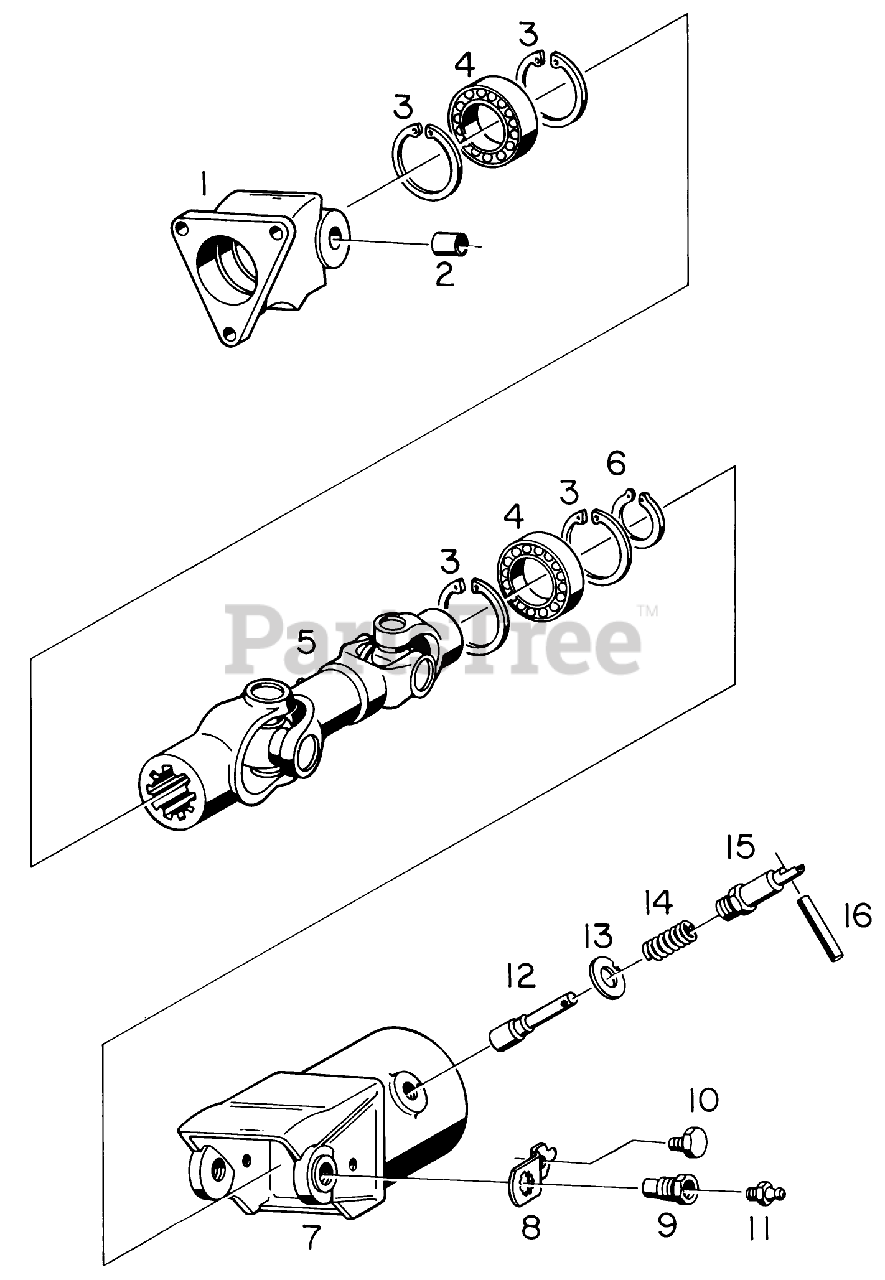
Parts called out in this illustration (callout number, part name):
2	Needle Bearing
7	Rear Housing
15	Bushing
